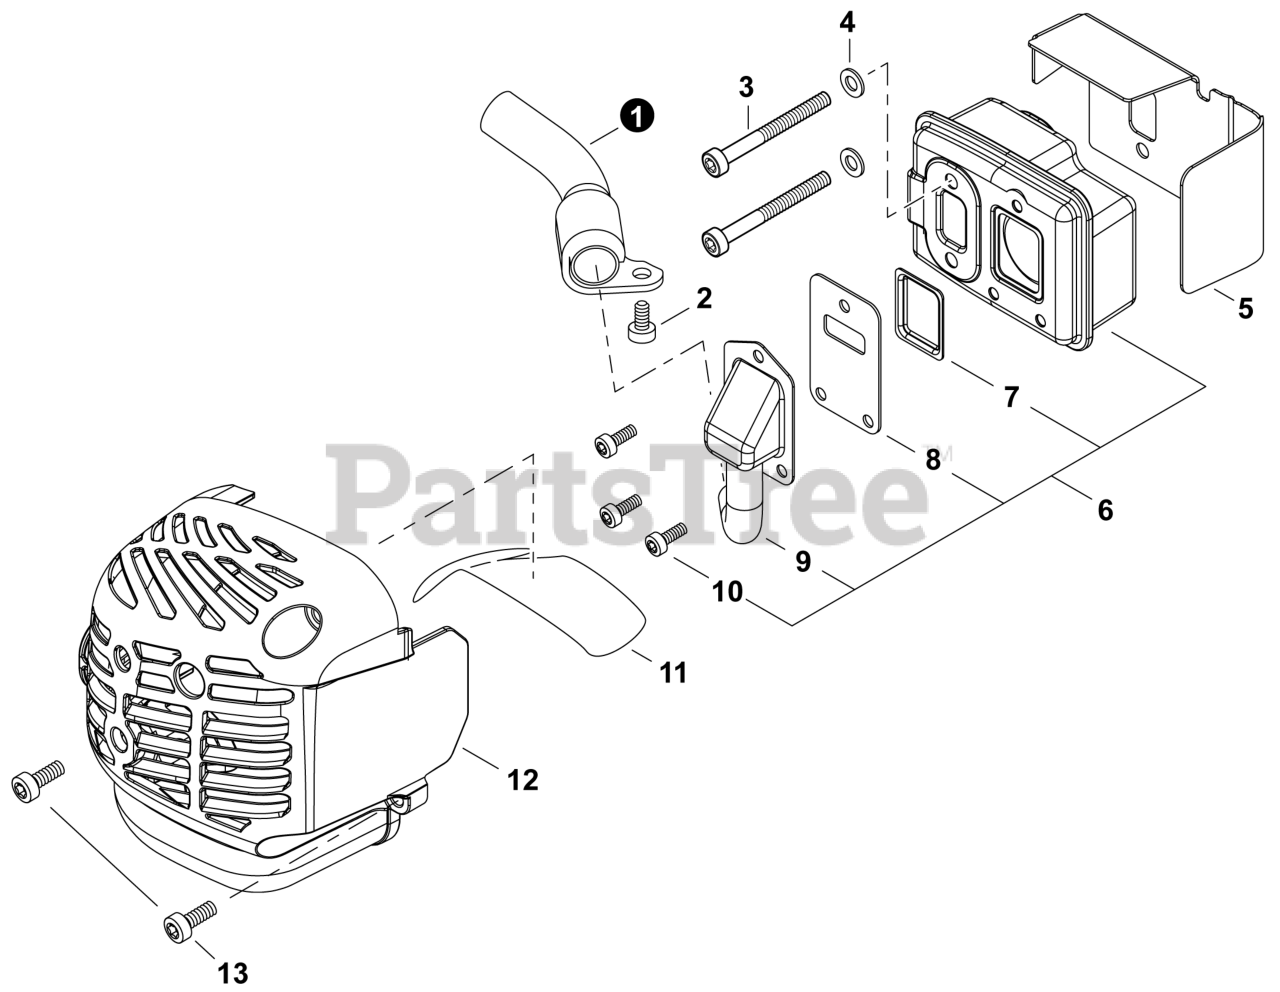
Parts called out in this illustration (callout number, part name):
1	GUIDE, EXHAUST
2	BOLT, TORX 5x10
3	BOLT, TORX 5x55
4	WASHER 5.5x12x0.8
5	HEAT SHIELD, EXHAUST
6	MUFFLER ASSY
7	SCREEN, SPARK ARRESTER
8	GASKET, EXHAUST
9	GUIDE, EXHAUST
10	BOLT, TORX 4x8
11	PLATE, INSULATOR
12	COVER, MUFFLER
13	BOLT, TORX 5x16
